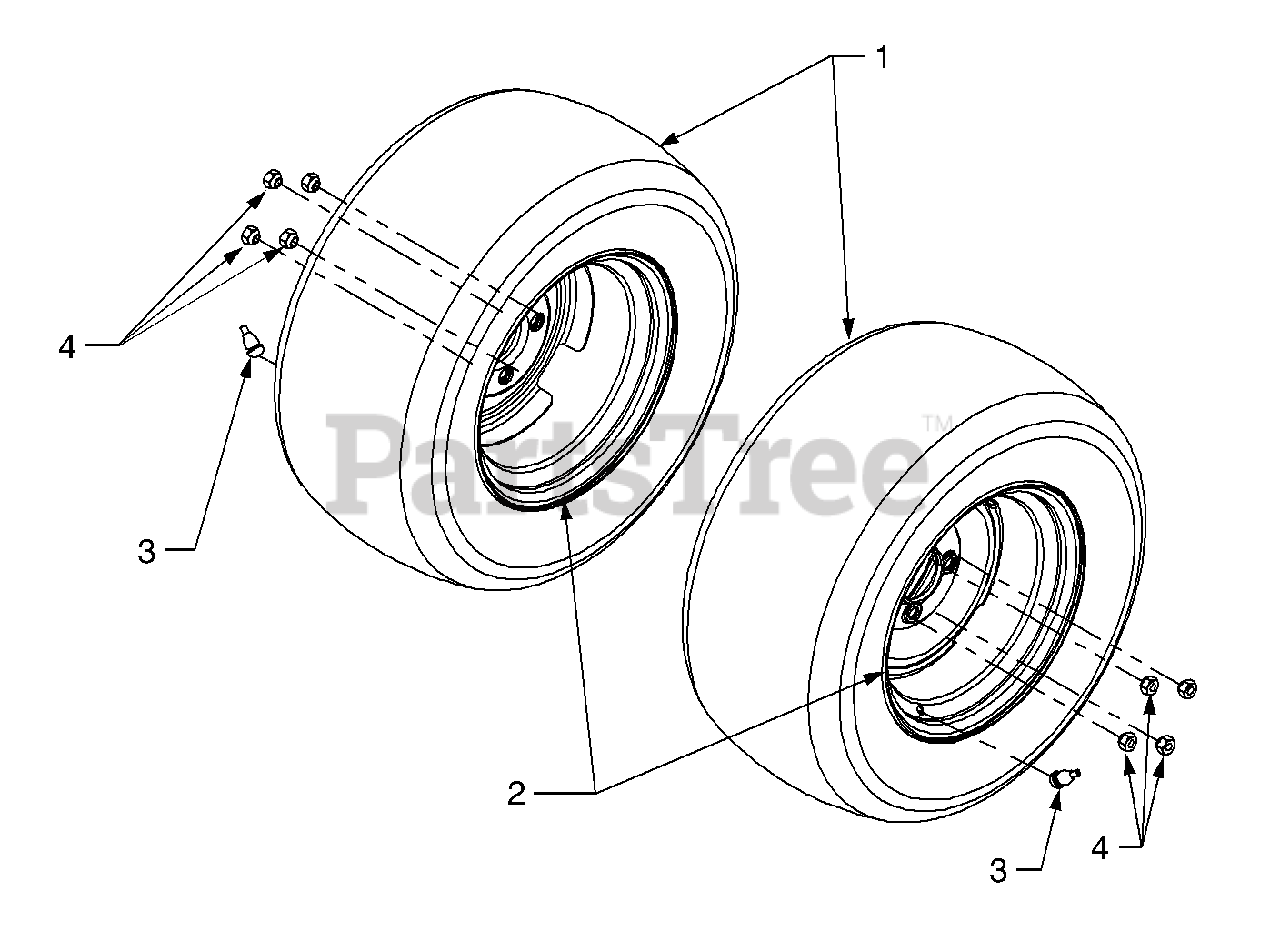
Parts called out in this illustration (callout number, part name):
1	Tire, Turf, 24 x 10.5 - 12
2	Rim Assembly, Wheel
3	Valve, Tubeless Air
4	Lug Nut, 7/16-14
